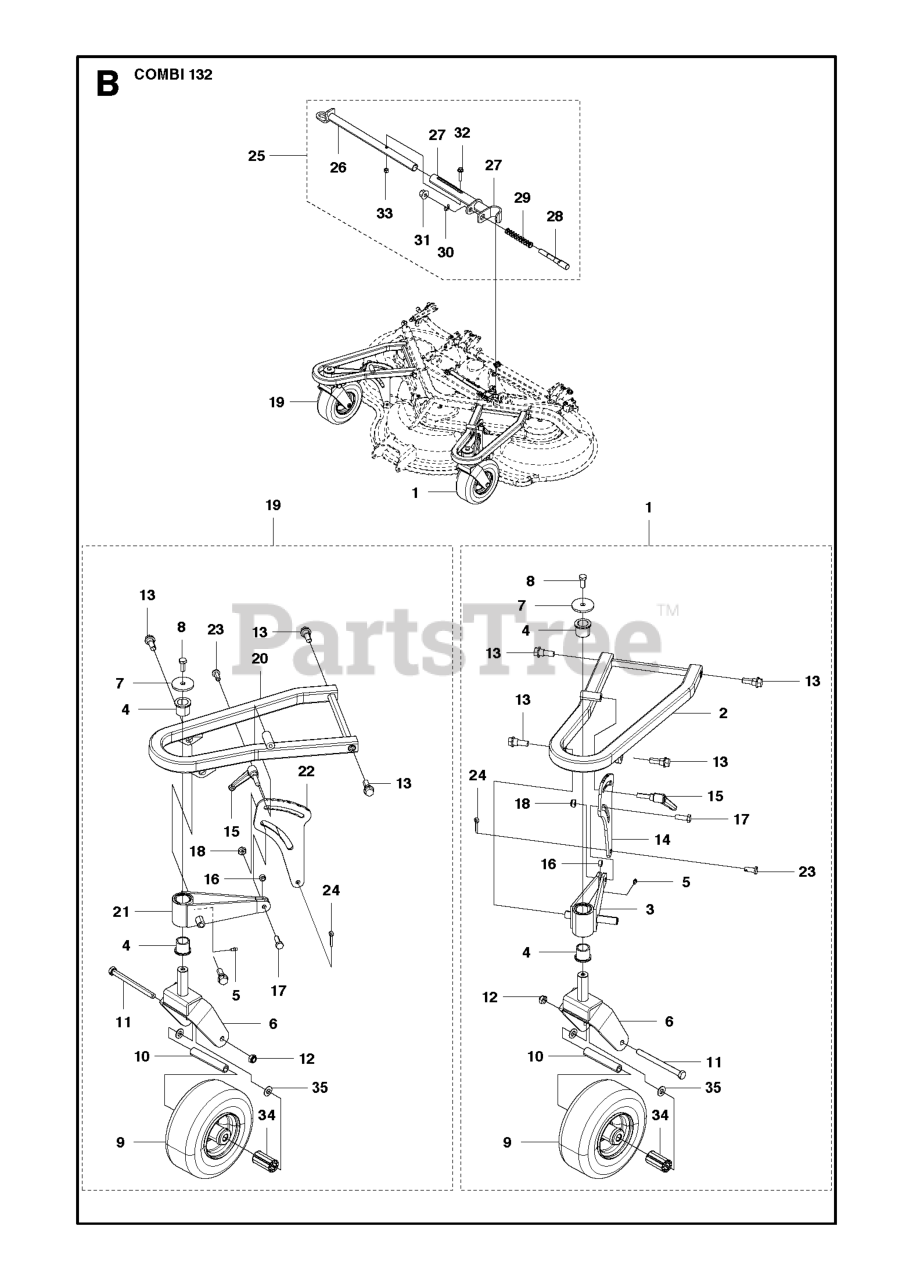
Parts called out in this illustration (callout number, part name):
1	WHEEL SUSPENSION LEFT
2	SUPPORTING ARM LEFT
3	PIVOT WHEEL SUPPORT LEFT
4	BEARING BUSHING BRASS
5	GREASE NIPPLE
6	FORK PIVOT WHEEL
14	SHEET HEIGHT ADJUSTER
15	TURNING KNOB M 10
16	SLEEVE PIVOT WHEEL SUPPORT
18	NUT
19	WHEEL SUSPENSION RIGHT
20	SUPPORTING ARM RIGHT
21	PIVOT WHEEL SUPPORT RIGHT
22	SHEET HEIGHT ADJUSTER
33	LOCKNUT M6
34	ROLLER BEARING
35	ENDCAP, NOTCHED
